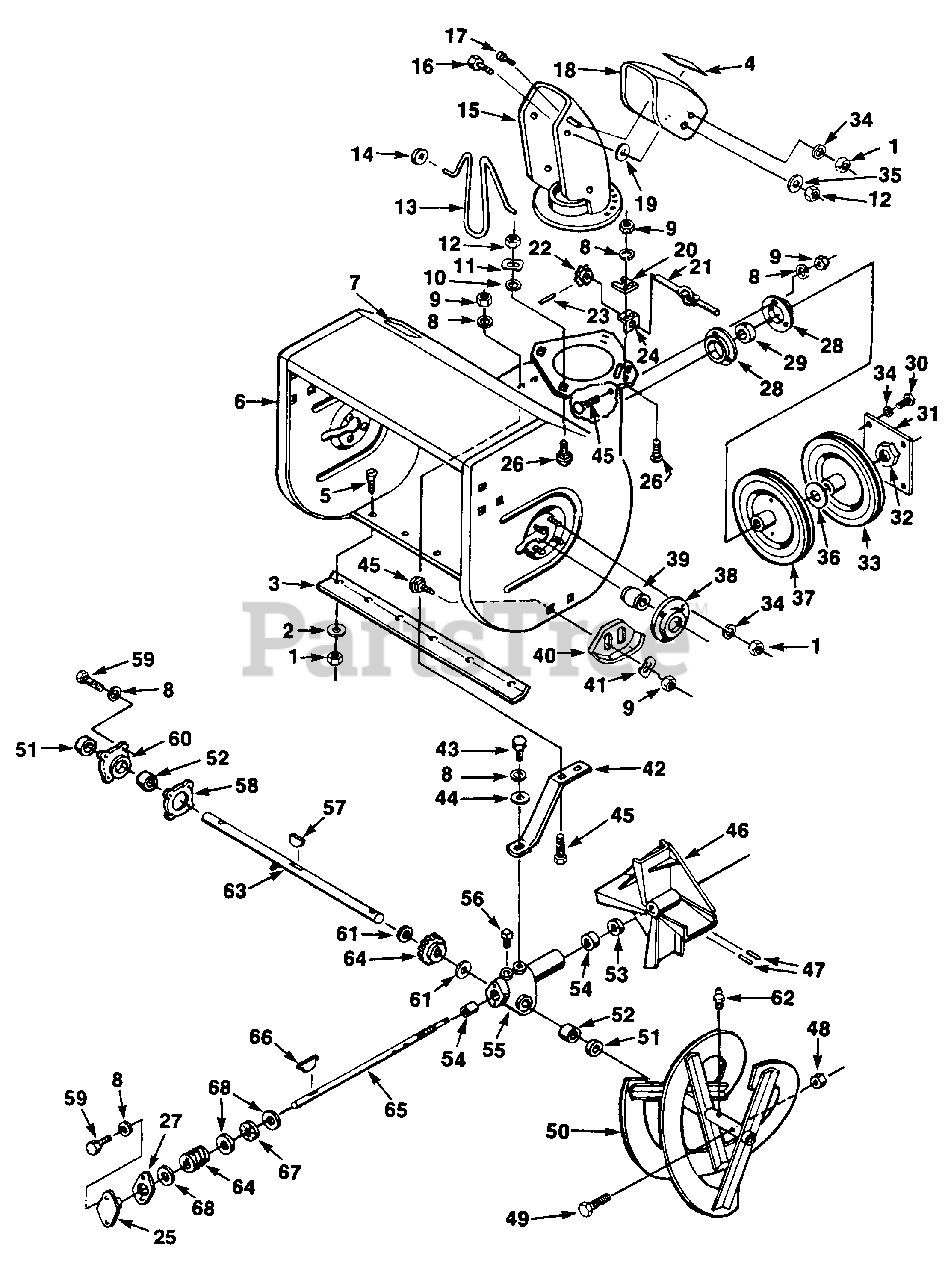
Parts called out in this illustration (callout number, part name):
1	NUT- Hex 1/4-20
2	WASHER- Hubbard
3	BLADE- Scraper (624)
4	DECAL- Impeller danger
5	SCREW- Slotted flat hd. 1/4-20 x 5/8"
6	IMPELLER COLLECTOR HOUSING ASSEMBLY
7	DECAL- Auger danger
8	WASHER- Lock med. 5/16"
9	NUT- hex 5/16-18
10	WASHER- Lock hvy. 5/16"
11	WASHER- Shakeproof chute retaining
12	NUT- Hex c/lock 5/16-18
13	GUARD- Chute
14	NUT- Tinnerman shield retaining
15	DISCHARGE CHUTE ASSEMBLY
16	SCREW- Hex hd. 5/16-18 x 5/8"
17	SCREW- Fill. hd. 1/4-20 x 1/2" deflector handle mtg.
18	DEFLECTOR- Chute
19	WASHER- Nylon
20	CLAMP- Chute retaining
21	ROD- Front chute adj.
22	SPROCKET- Chute adjusting
23	PIN- Roll 1/8 x 3/4"
24	BRACKET- Chute control
25	COVER- Gear housing end
26	BOLT- Carr. 5/16-18 x 5/8"
27	GASKET- End cover
29	BEARING- Impeller shaft
30	SCREW- Hex hd. 1/4-20 x 1/2"
31	PLATE- Traction face
32	NUT- Hex c/lock 1/2-13
33	TRACTION PULLEY & BEARING ASSEMBLY
34	WASHER- Lock hvy. 1/4"
35	WASHER- Cupped spring
36	WASHER- Thrust
37	PULLEY- Driven
38	RETAINER- Collector bushing
39	BUSHING- Collector
40	SKID- Collector
41	WASHER- Shakeproof 5/16"
42	SUPPORT- Gear box
43	SCREW- Hex hd. cap 5/16-18 x 7/8"
44	WASHER- SAE flat 5/16"
45	BOLT- Shnk. carr. 5/16-18 x 3/4"
46	IMPELLER ASSEMBLY
47	PIN- Roll 1/4 x 1 1/2"
48	NUT- Hex GRIPCO C/lock 1/4-20
49	BOLT- Collector shear
50	COLLECTOR ASSEMBLY R.H. (624)
51	SEAL- Collector shaft
52	BEARING- Collector shaft
53	SEAL- Impeller shaft
54	BEARING- Impeller shaft
55	GEAR HOUSING ASSEMBLY
56	PLUG- NPT sq. hd. pipe 1/4"
57	KEY- Woodruff #A 1/4 x 7/8"
58	GASKET- Gear housing cover
59	SCREW- Hex hd. cap 5/16-18 x 3/4"
60	GEAR HOUSING COVER
61	WASHER- Thrust
62	GREASE FITTING
63	SHAFT COLLECTOR
64	SET- Worm & Worm Wheel
65	SHAFT- Impeller
66	KEY- Morton HP-606 3/16 x 3/4"
67	BEARING- Thrust
68	RACE- Thrust bearing
